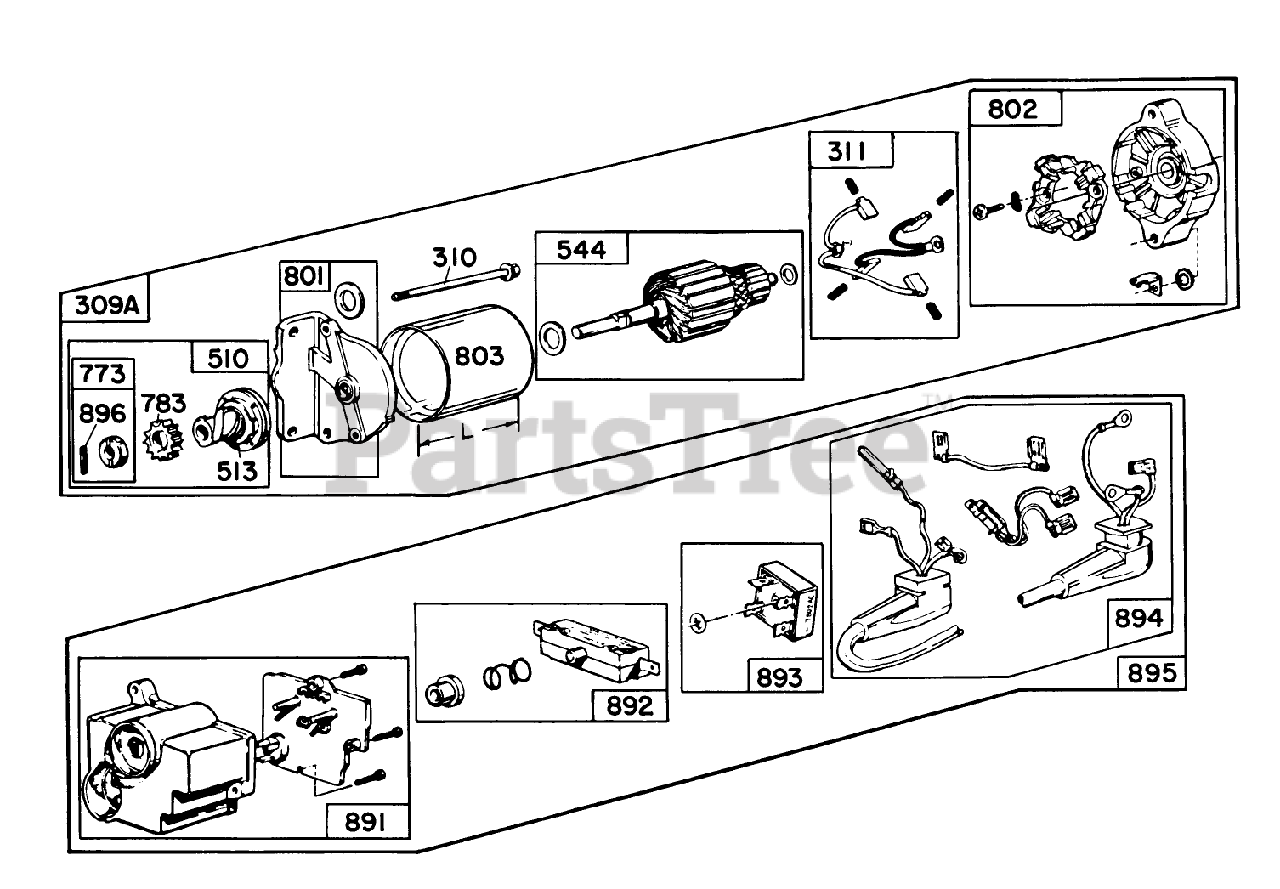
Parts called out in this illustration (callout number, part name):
309	Motor Drive Assembly
310	Thru Bolt Assembly
311	Brush Assembly
510	Drive Assembly
513	Clutch Assembly
544	Armature Assembly
773	Gear-Starter
801	Drive End Cap Assembly
802	Comm. End Cap Assembly
803	Housing Assembly
891	Housing Group
892	Switch Group
893	Rectifier
894	Lead Group
895	Control Group
